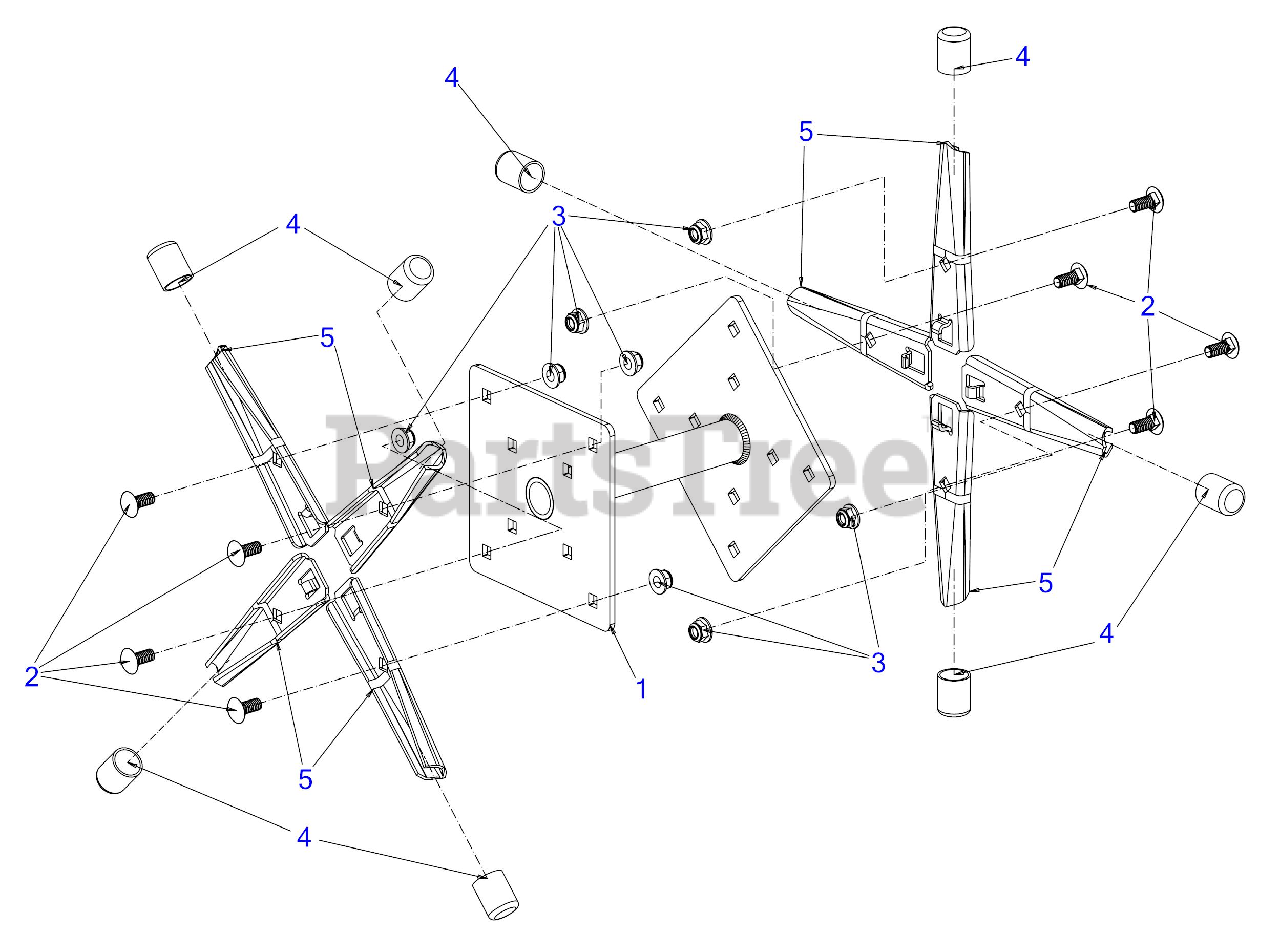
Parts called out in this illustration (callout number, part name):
1	AERATOR DOUBLE WELD ASSEMBLY
2	CARRIAGE BOLT 5/16-18 x .75
3	FLANGE LOCK NUT 5/16-18
4	N/A (Not Serviceable)
5	AERATOR SPIKE
